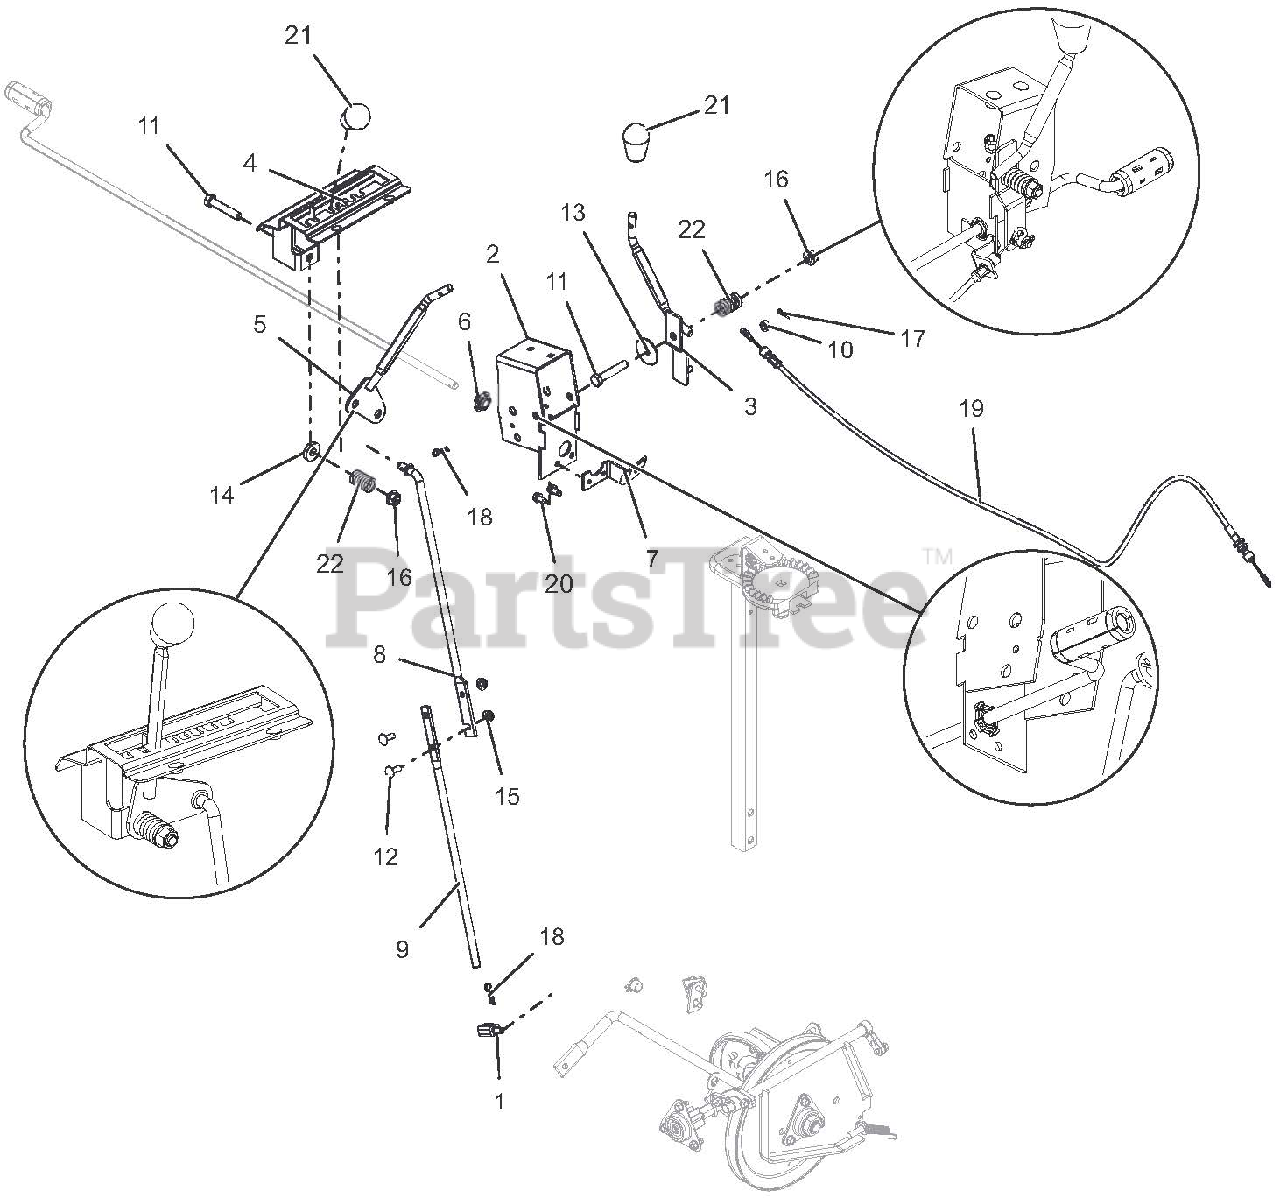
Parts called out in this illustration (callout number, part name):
1	PIVOT,SHIFT ROD .375-16(TRUNN)
2	WELDMENT, BRACKET INTERLOCK
3	WELDMENT, CONTROL LEVER (DEFL)
4	WELDMENT, DETENT PLATE-COMPACT
5	LEVER, CONTROL-SHIFT(WELDMENT)
6	CRANK BUSHING, NYLON CHUTE BK
7	ANCHOR, DEFLECTOR CABLE
8	ROD, SHIFT - UPPER
9	ROD, SHIFT - LOWER
10	BSHG-SLV .265X.500X.219
11	@BLT-HEX .38-16X2.00 GR5 YWZC
12	@BLT-RDHDSQNK .25-20X.75 G5YZ
13	WSHR-FL-STL .380X1.50X.062 YWZ
14	WSHR-FL-STL .406X1.00X.188 YWZ
15	@NUT-LK-CTR-FLG .25-20 YWZC
16	@NUT-LK-TOP-FLG .38-16 YWZC
17	PIN-HAIR INT .06X.18X.77
18	PIN-HAIR INT .08X.18X1.18 YWZC
19	CABLE, DEFLECTOR CAP SNO-TEK
20	SCR-TAP .25-20X.50 HWH TR YWZ
21	KNOB,SOFT TEARDROP,PUSH-ON BLK
22	SG-COMP .125X.781X1.250
